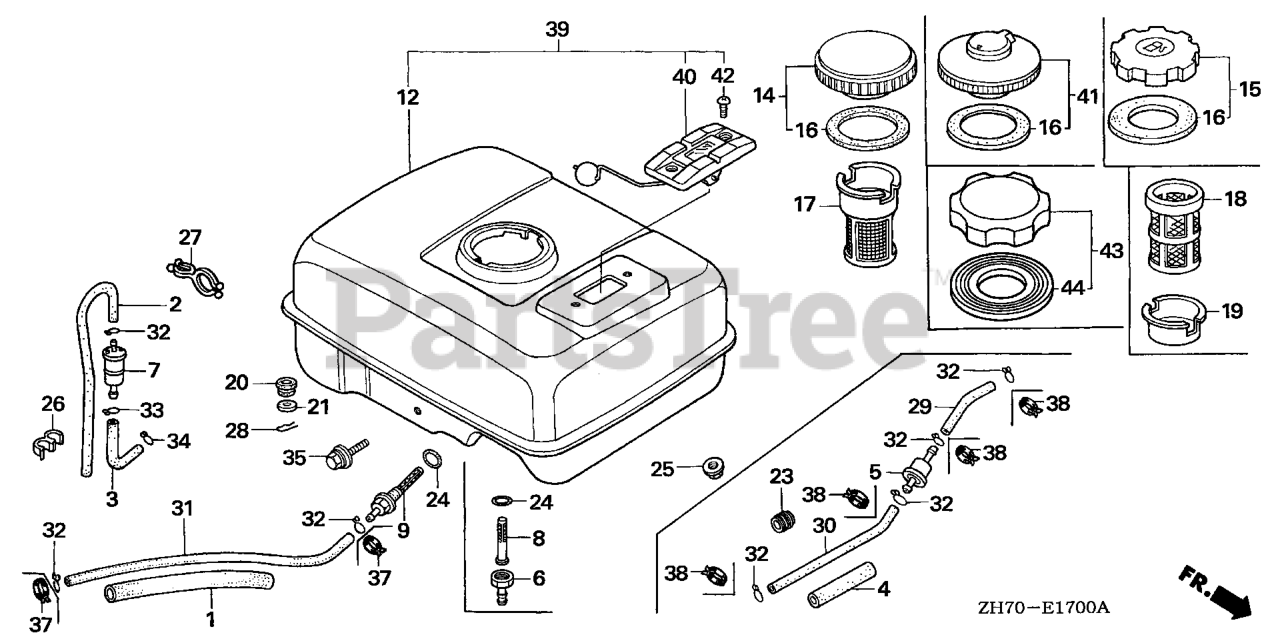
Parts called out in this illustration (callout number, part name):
1	RUBBER, SUPPORTER (107MM)
9	JOINT, FUEL TANK
12	TANK, FUEL *NH31* (MCKINLEY WHITE)
12	TANK, FUEL *NH1* (BLACK)
14	CAP, FUEL FILLER Use from Engine SN 1211508 to 1518838.
14	CAP, FUEL FILLER
15	CAP, FUEL FILLER (BLACK) Use up to Engine SN 2115700.
15	CAP, FUEL FILLER (CHROME PLATED)
15	CAP COMP
16	GASKET, FUEL FILLER CAP (39X58X3) (NOT AVAILABLE)
16	GASKET, FUEL FILLER CAP Use from Engine SN 1543258.
16	GASKET, FUEL FILLER CAP (39X58X3)
24	O-RING (14MM) (ARAI) Use up to Engine SN 2949254.
25	NUT, FLANGE (6MM)
31	BULK HOSE, FUEL (4.5X3000) (Honda Code 5137104). (4.5X140)
32	CLIP, TUBE (B8)
35	BOLT, FLANGE (6X29)
43	CAP, FUEL FILLER (CHROME PLATED)
43	CAP COMP
43	CAP, FUEL FILLER (CHROME PLATED)(TOUYOUSYA)
44	GASKET, FUEL FILLER CAP (39X62X3) (TOUYOUSYA)
